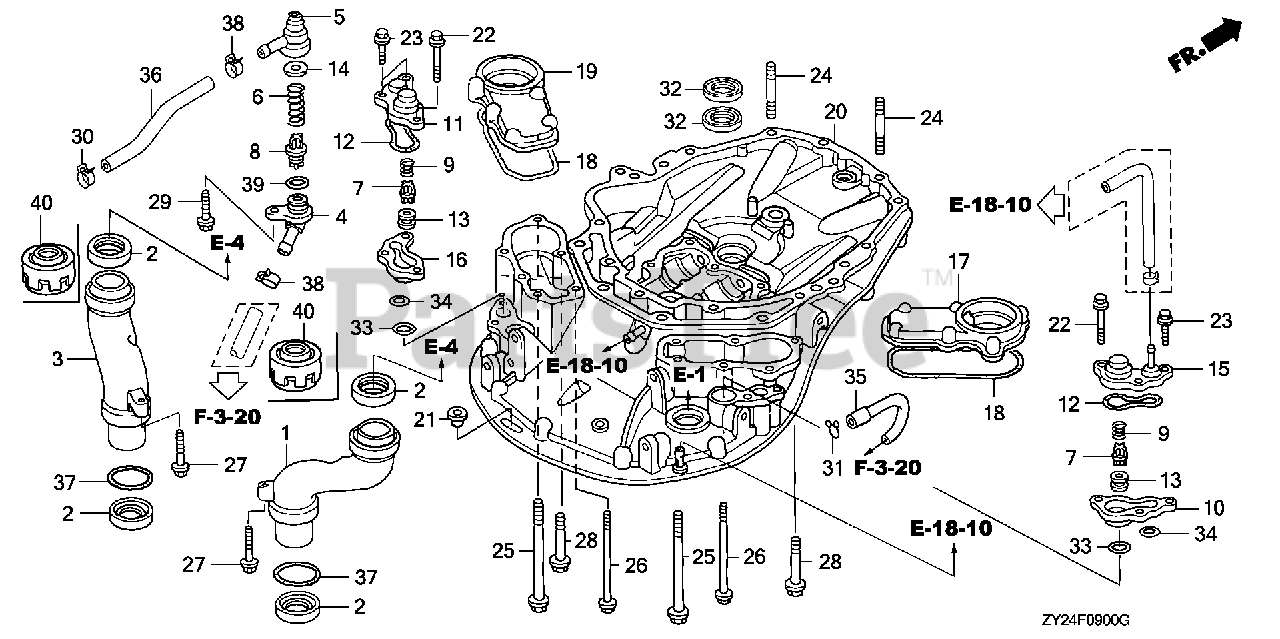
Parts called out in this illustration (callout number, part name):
1	GUIDE, R. EX. *TGRAY* (GRAY)
2	SEAL, EX. GUIDE
3	GUIDE, L. EX. *TGRAY* (GRAY)
4	COVER, FLUSH VALVE *NH8* (DARK GRAY)
5	CASE, FLUSH VALVE
6	SPRING, FLUSH VALVE
7	VALVE, RELIEF
8	VALVE, FLASH
9	SPRING, RELIEF VALVE
10	SPACER, R. RELIEF VALVE *TGRAY* (GRAY)
11	COVER, L. RELIEF VALVE
12	GASKET, RELIEF VALVE COVER
13	GASKET, RELIEF VALVE
14	GASKET, FLASH VALVE
15	COVER, R. RELIEF VALVE
16	SPACER, L. RELIEF VALVE *TGRAY* (GRAY)
17	COVER, R. WATER JACKET *NH8* (DARK GRAY) (NOT AVAILABLE)
18	GASKET, WATER JACKET COVER
19	COVER, L. WATER JACKET *NH8* (DARK GRAY)
20	CASE, MOUNT *NH8* (DARK GRAY)
21	RUBBER, MOUNT CASE SEAL
22	BOLT, FLANGE (6X22)
23	BOLT, FLANGE (6X32)
24	BOLT, STUD (10X45)
25	BOLT, FLANGE (8X100)
26	BOLT-WASHER (6X121)
27	BOLT, FLANGE (6X40)
28	BOLT, FLANGE (8X30)
29	BOLT-WASHER (6X29)
30	CLIP, TUBE
31	CLIP, TUBE (B10)
32	SEAL, WATER (22X35X7)
33	O-RING (33.5X2)
34	O-RING (23.5X2)
35	TUBE, WATER CHECK
36	TUBE, FLUSH VALVE
37	O-RING (49.4X3.1)
38	CLIP, TUBE (B12.5)
39	O-RING (16MM)
